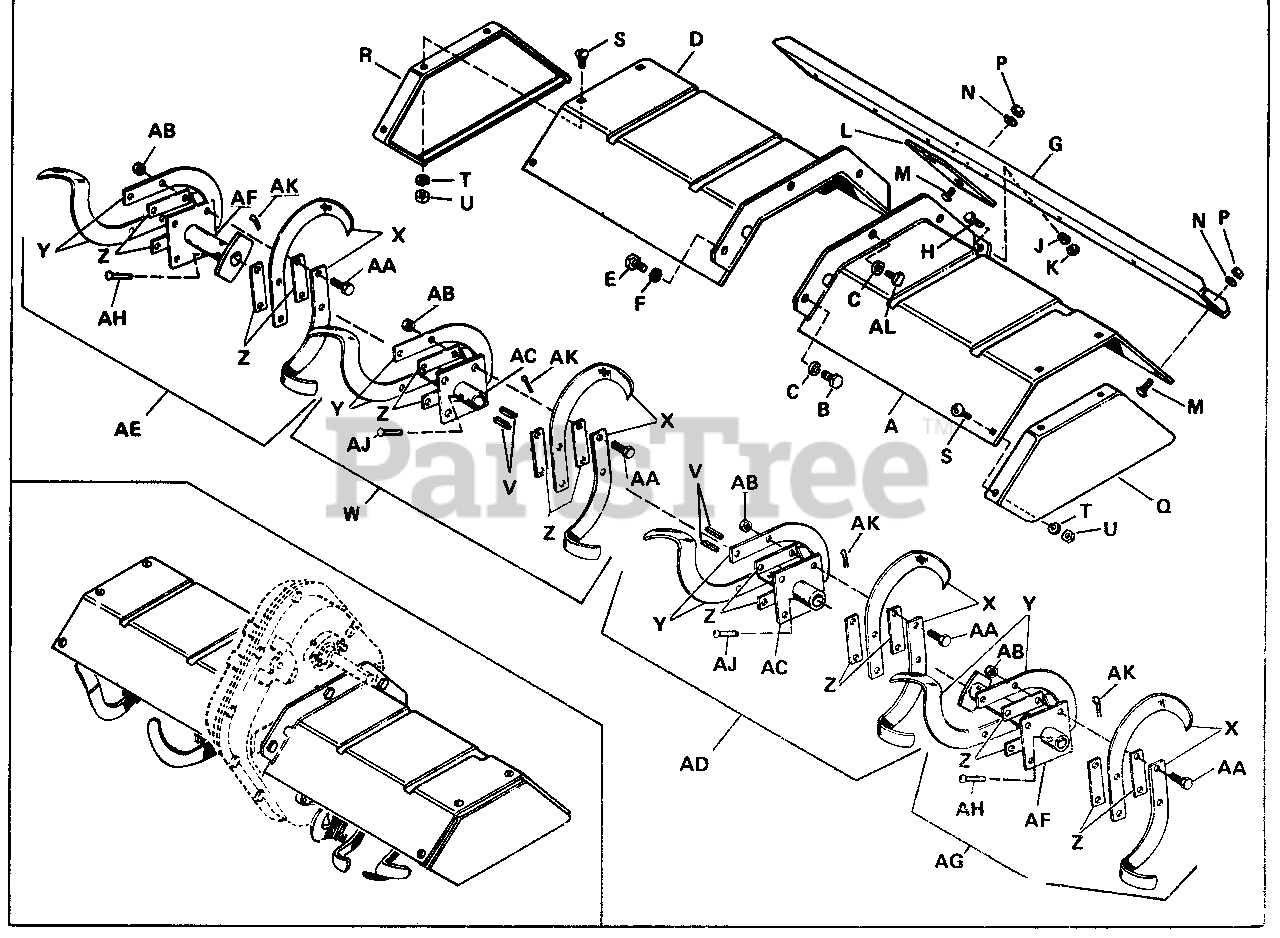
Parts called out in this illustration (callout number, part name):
A	Deflector Assembly, L.H.
B	Hex. Capscrew, 3/8"-16 x 1"
C	Lock Washer, 3/8"
D	Deflector Assembly, R.H.
E	Hex. Capscrew, 3/8"-16 x 1"
F	Lock Washer, 3/8"
G	Reinf. Channel
H	Hex. Capscrew, 3/8"-16 x 7/8"
J	Lock Washer, 3/8"
K	Full Hex. Nut, 3/8"-16
M	Carriage Bolt, 5/16"-18 x 3/4"
N	Lock Washer, 5/16"
P	Full Hex. Nut, 5/16"-18
Q	Plate Deflector End, L.H.
R	Plate Deflector End, R.H.
S	Carriage Bolt, Short, 5/16"-18 x 1/2"
T	Lock Washer, 5/16"
U	Full Hex Nut, 5/16"-18
W	Inner Tine Blade Assembly, R.H.
X	Tine Blade, L.H.
Y	Tine Blade, R.H.
Z	Spacer, 1/4" x 1" x 4-1/4
AA	Hex Capscrew, 7/16"-20 x 2"
AB	Full Hex. Locknut, 7/16"-20
AC	Hub. Attach. Assembly
AD	Inner Tine Blade Assembly, L.H.
AE	Outer Tine Blade Assembly, R.H.
AF	Tine Plate Assembly
AG	Outer Tine Blade Assembly
AH	Pin Tine Shaft
AK	Cotter Pin, 1/8" x 3/4"
AL	Hex Capscrew, 3/8"-16 x 5/8"
